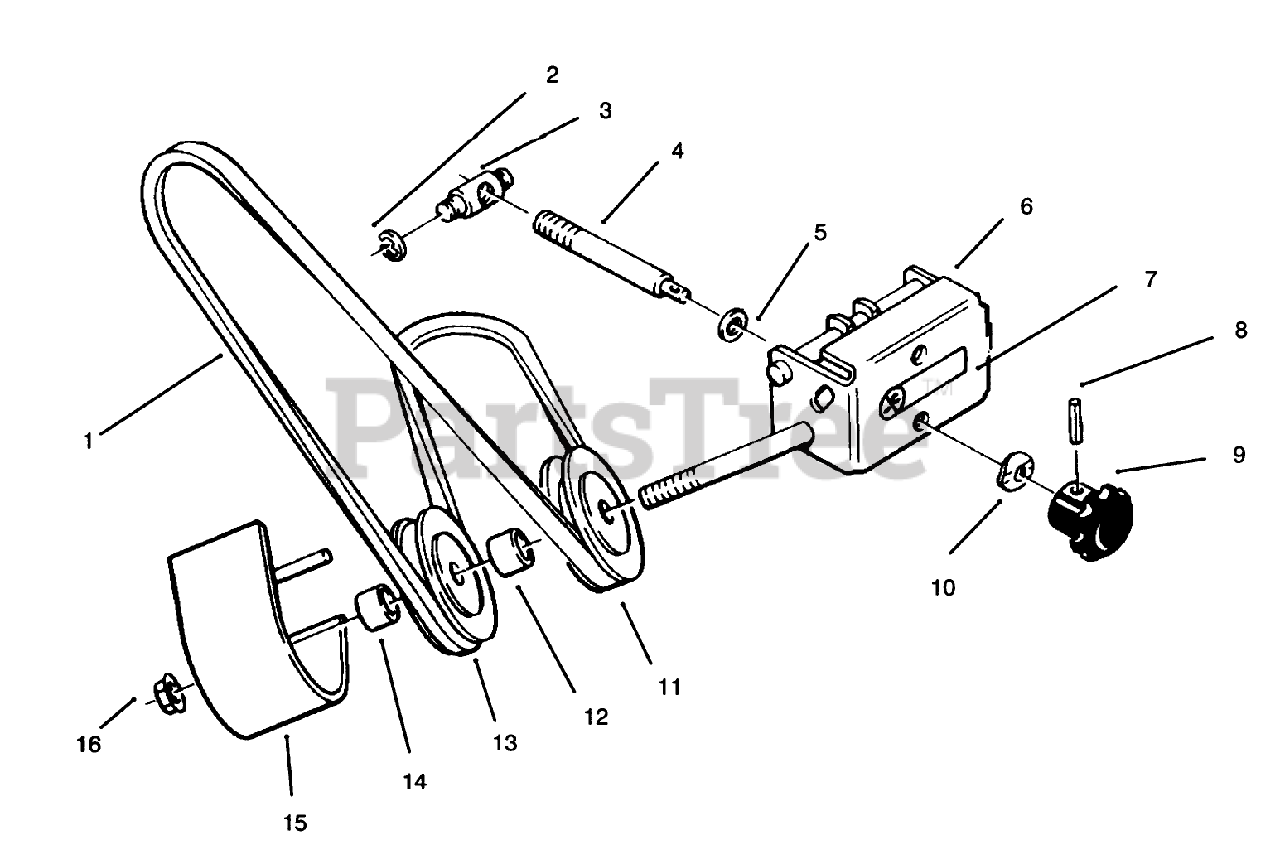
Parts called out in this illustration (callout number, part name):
1	V-BELT
2	RING-RETAINING
3	TRUNNION-DOUBLE
4	ROD ADJ
5	WASHER-FLAT
7	DECAL-ATTACH A-MATIC
8	PIN-ROLL
9	KNOB-ADJUSTMENT
10	WASHER-SPRING
11	PULLEY-IDLER
12	SPACER
13	PULLEY-FLAT IDLER
14	SPACER-OUTER
16	NUT
